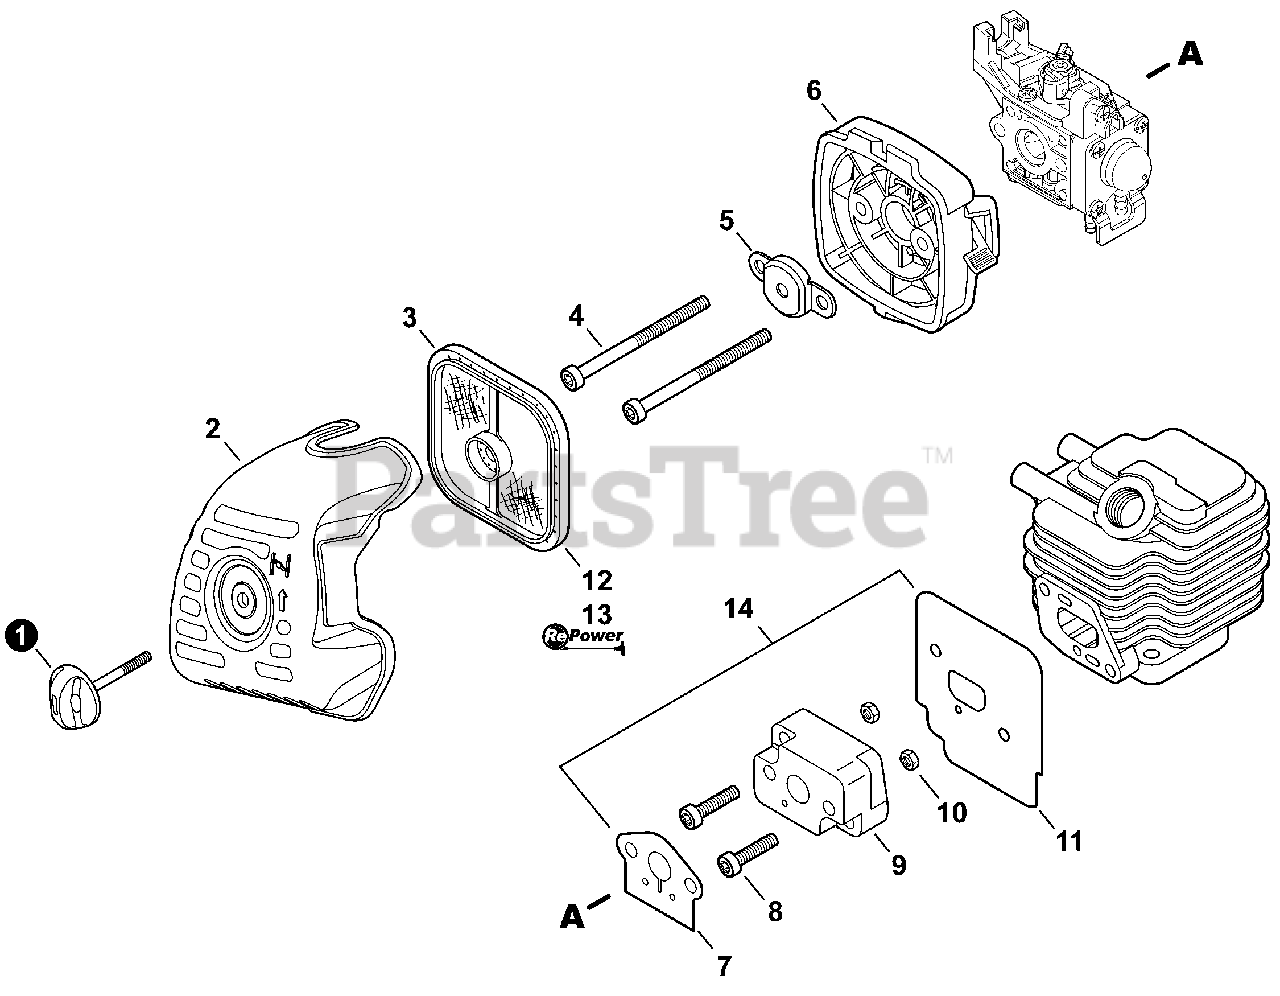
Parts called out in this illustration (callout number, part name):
1	THUMBSCREW
2	COVER, AIR FILTER
3	FILTER, AIR - DOUBLE LAYER
4	SCREW - 5×65 -- TORX
5	PLATE, PREVENT
6	CASE, AIR FILTER
7	GASKET, INTAKE
8	SCREW - 5×20
9	INSULATOR, INTAKE
11	SHIELD, INTAKE
12	TUNE-UP KIT - REPOWER
13	FILTER KIT - REPOWER
14	GASKET KIT
